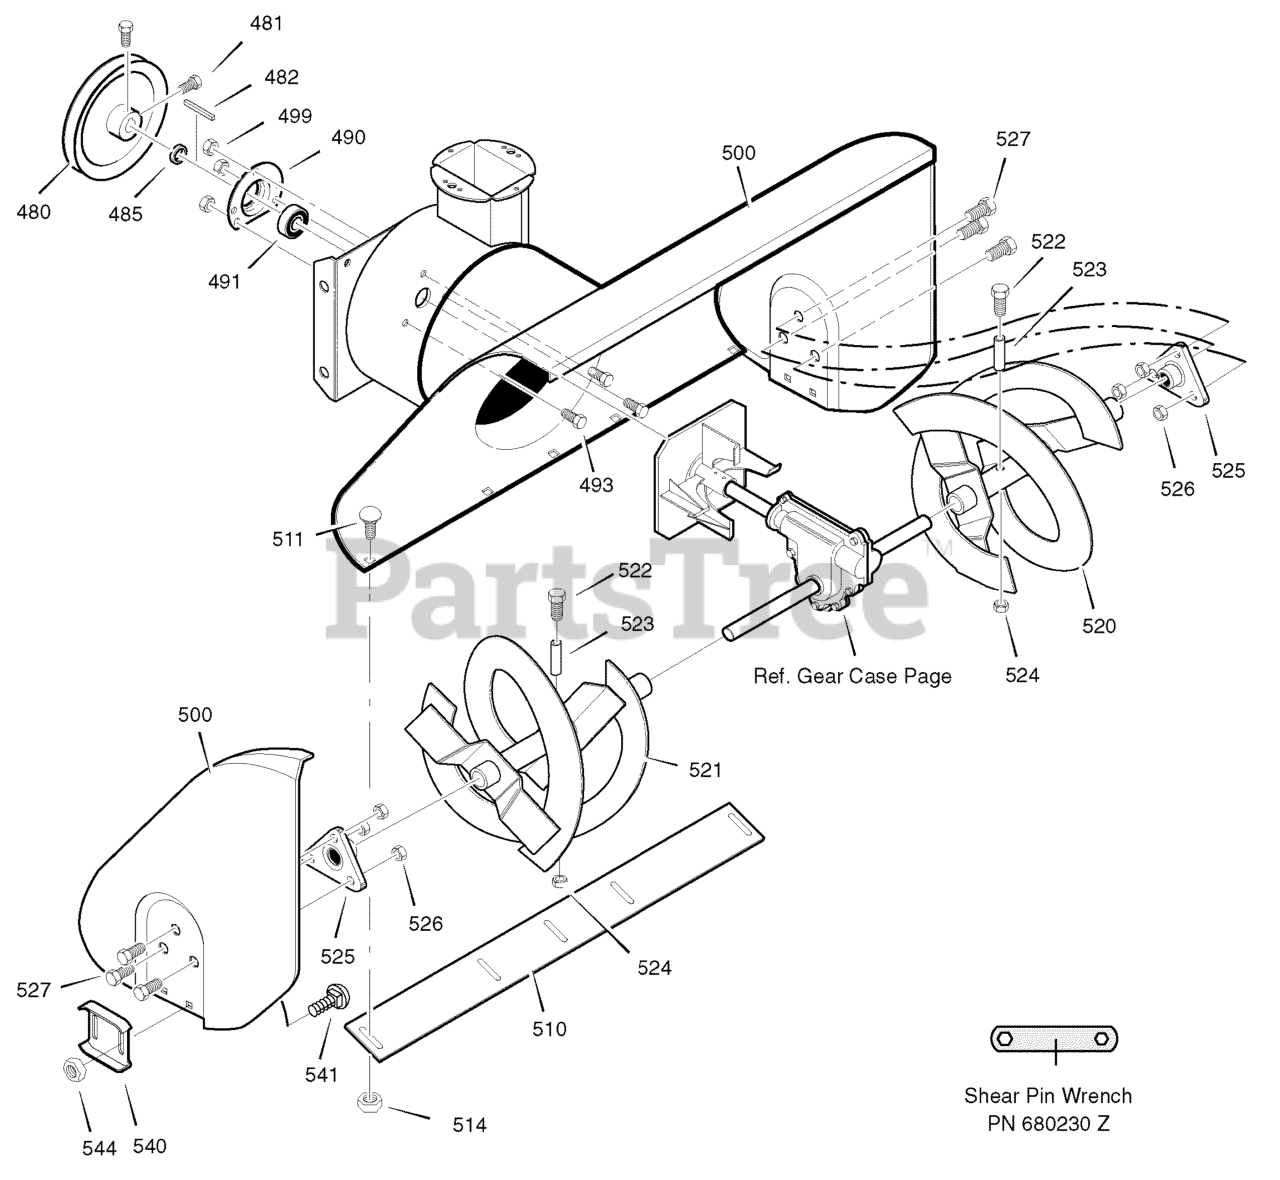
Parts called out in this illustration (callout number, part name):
480	PULLEY, 4L 6.12X .67
481	SCREW, 5/16-18 x 0.63
482	KEY, SQUARE 3/16 X 3/4
485	SPACER, FRICTION PULLEY
490	RETAINER, BALL BRNG
491	BEARING, BALL
493	BOLT, HEX 5/16-18X .50
499	NUT, 5/16-18 HEXWDFLLK
500	HOUSING, ASSY
510	BLADE, SCRAPER 24"
511	BOLT, 1/4-20X.75
514	NUT, 1/4-20
520	AUGER, ASSY, LH
521	AUGER, ASSY, RH
522	SCREW, 1/4-20X1.75
523	SPACER, SLEEVE
524	NUT, 1/4-20
525	BEARING, FLANGE
526	NUT, 5/16-18
527	SCREW, 5/16-18 x 0.75
540	SKID, HEIGHT ADJUST
541	BOLT, 5/16-18 X .75
544	NUT, 5/16-18
